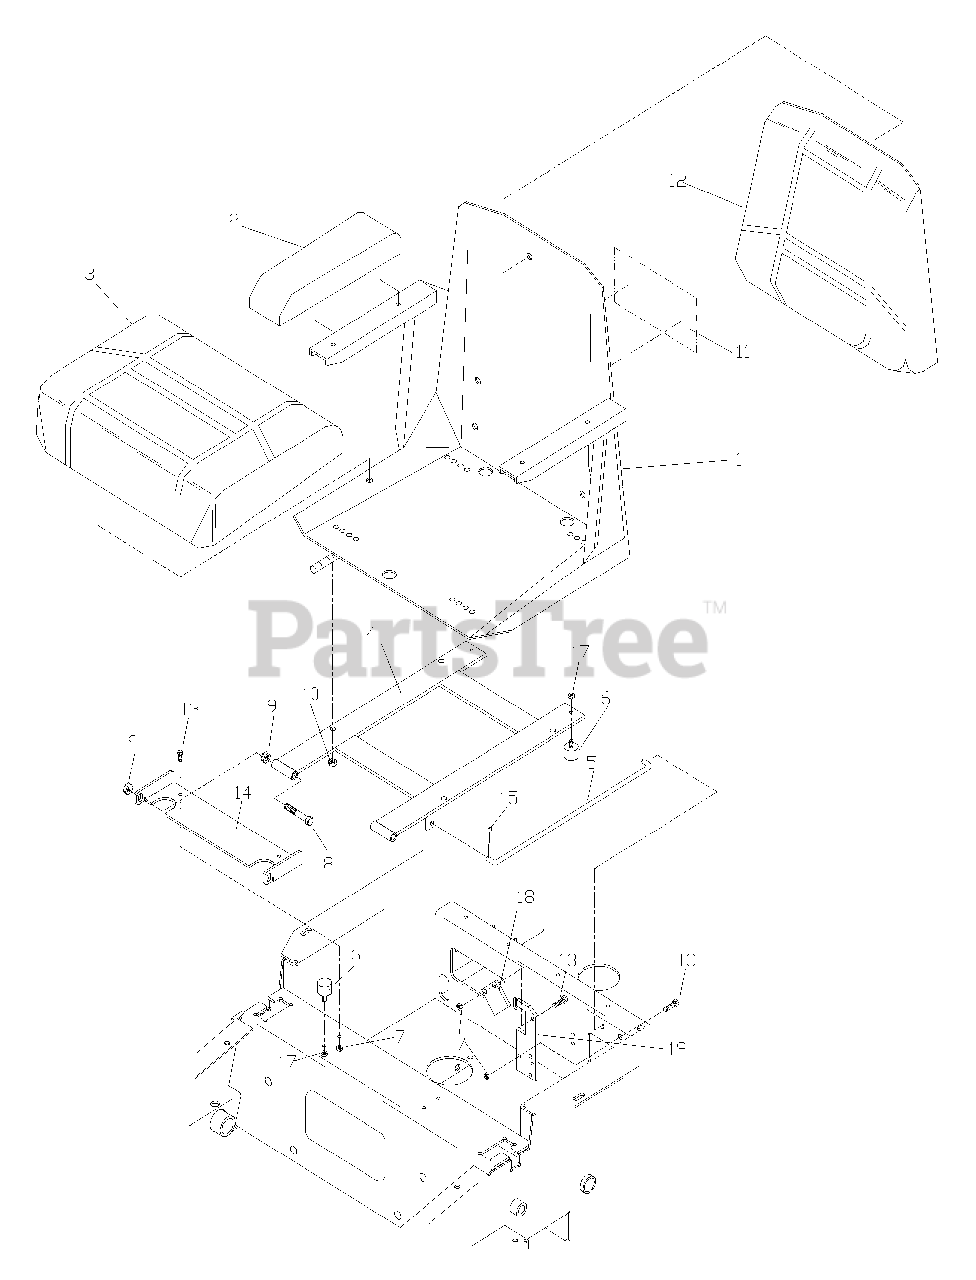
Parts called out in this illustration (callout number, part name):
1	SEAT, COMPLETE
2	ARM REST CUSHION
3	SEAT CUSHION W/SWITCH
4	SEAT MOUNT
6	STUD / PLATE MOUNT
7	1/4C LOCKNUT
8	HCS 3/8C X 3
9	NUT 3/8C CTR. LOCK
10	NUT 5/16C CTR. LOCK
11	DECAL, CROWN
12	SEAT BACK CUSHION
13	HCS 1/4C X 3/4
14	SEAT BKT. W/DECAL
15	COTTER PIN
17	NUT 1/4C NYLOC
18	SEAT LATCH
19	SEAT LATCH MOUNT
